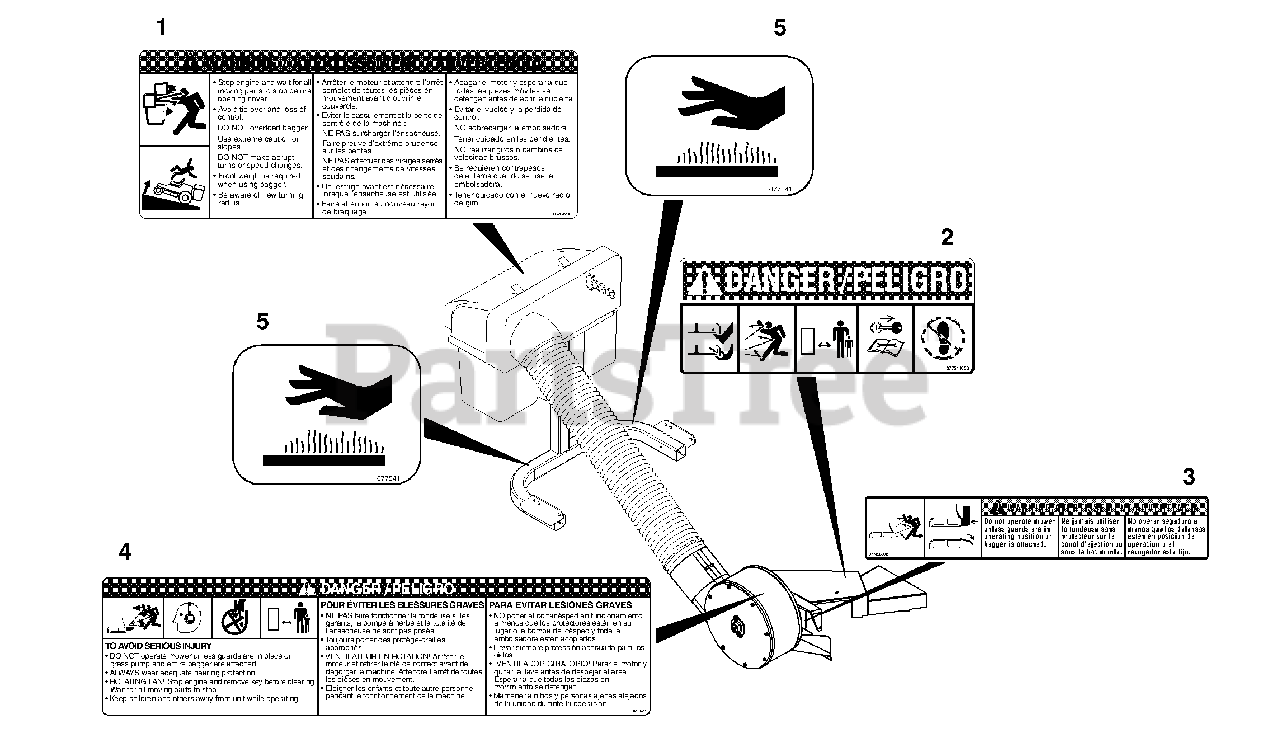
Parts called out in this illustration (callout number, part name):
1	Decal-Warning, Bagger Cover
2	Decal, Mower Pan Head Danger
3	Decal, Warning
4	Decal-Caution, Grass Pump
5	Decal, Hot Surface
